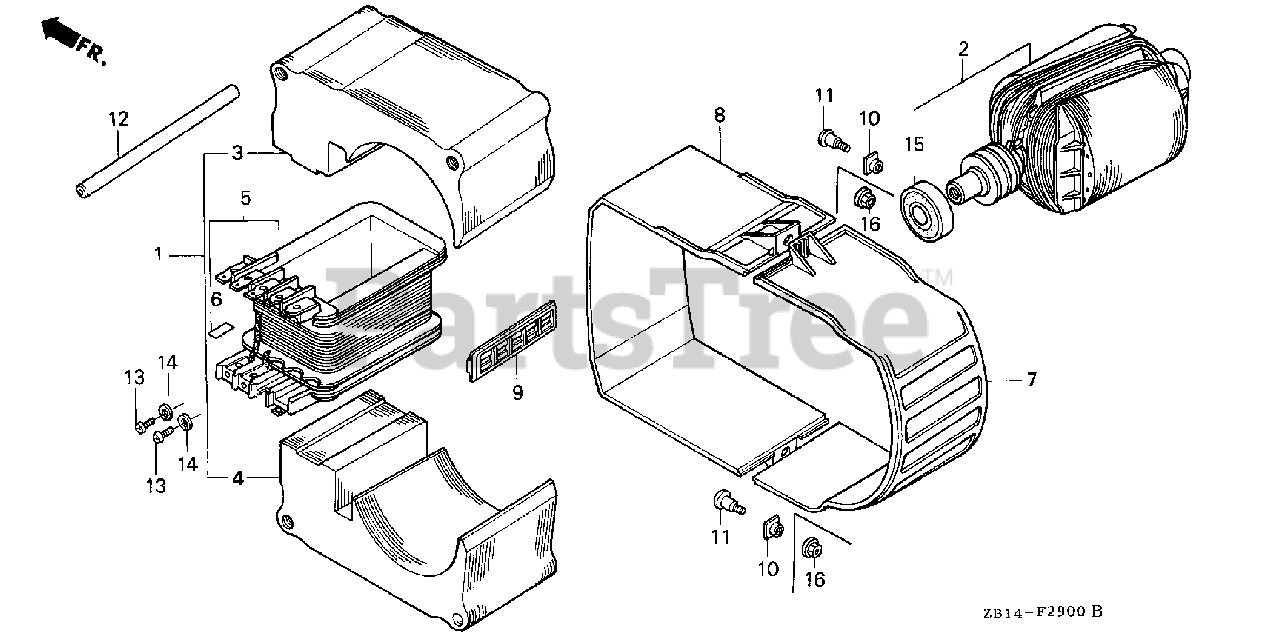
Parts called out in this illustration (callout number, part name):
1	CORE SET, STATOR
2	ROTOR (EZ-R)
5	BOBBIN, STATOR COIL
6	MARK, WIRE COLOR
7	COVER, R. STATOR (NOT AVAILABLE)
8	COVER, L. STATOR
9	STIFFENER, STATOR (NOT AVAILABLE)
10	NUT, SPECIAL (5MM)
11	BOLT, STATOR COVER SETTING
12	PIN, DOWEL (11X121)
13	SCREW, PAN (5X8)
14	WASHER, SPRING (5MM)
15	BEARING ASSY. (6203)
15	BEARING, RADIAL BALL (6203UU)
